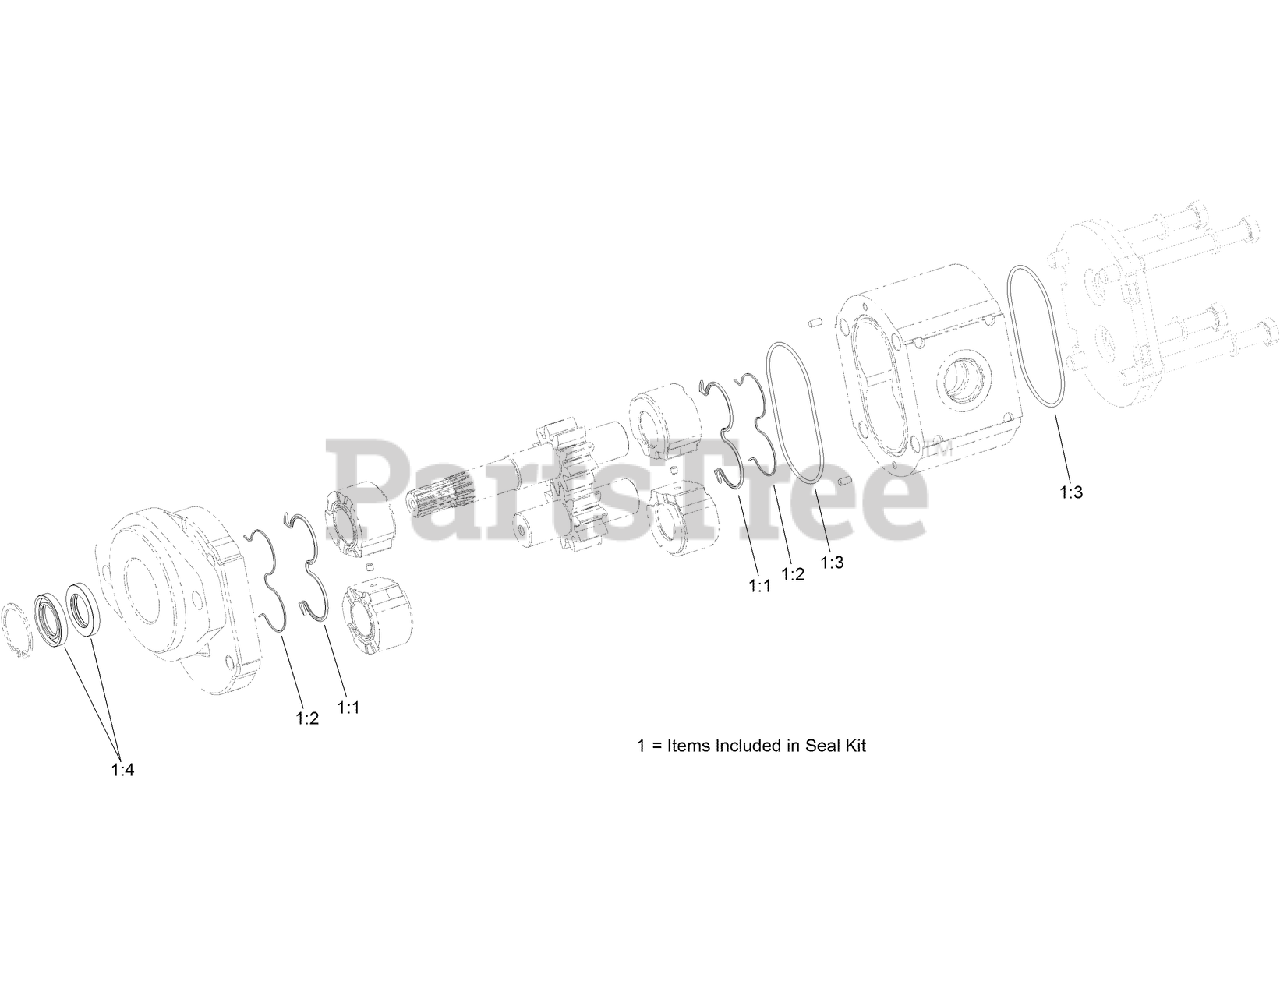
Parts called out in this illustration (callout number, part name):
1	SEAL KIT
1:1	SEAL
1:2	RING-ANTIEXTRUSION
1:3	Deck ASM
1:4	SEAL-Shaft
